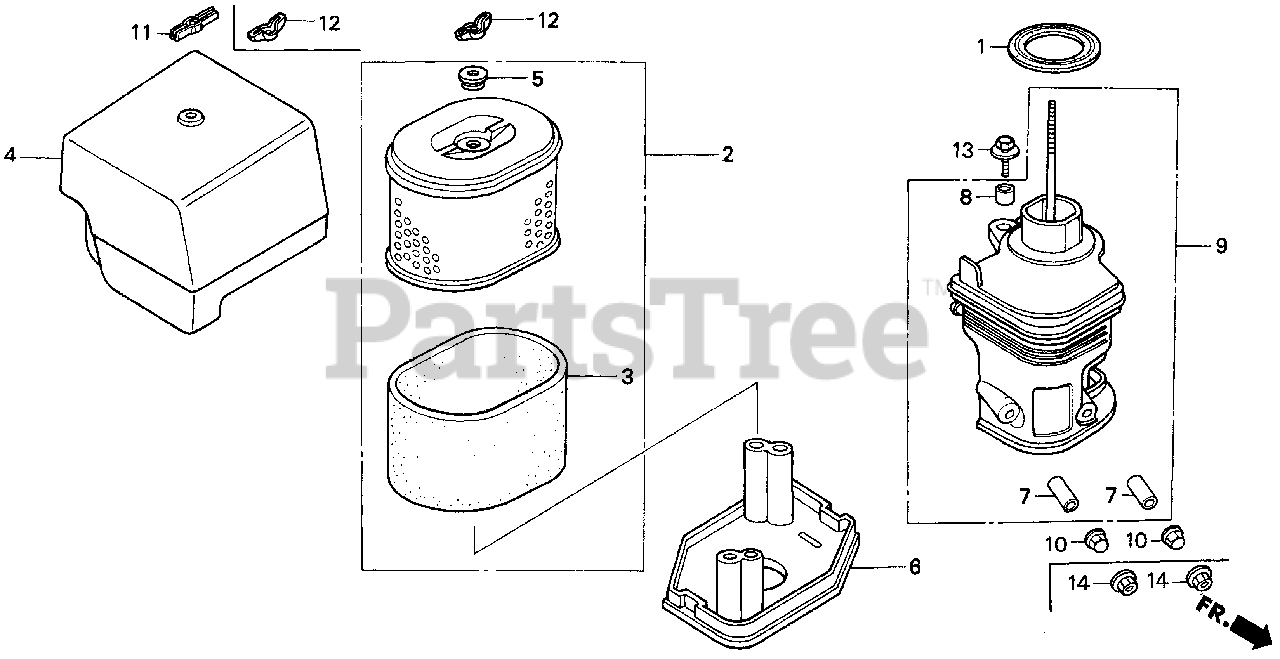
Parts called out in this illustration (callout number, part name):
1	GASKET, ELBOW
2	ELEMENT, AIR CLEANER (DUAL)
3	FILTER (OUTER)
4	COVER, AIR CLEANER
5	GROMMET, AIR CLEANER
7	COLLAR, AIR CLEANER
8	COLLAR B, AIR CLEANER
9	ELBOW, AIR CLEANER
11	WINGNUT (6MM)
12	WINGNUT, TOOL BOX SETTING
13	BOLT-WASHER (6X22)
13	BOLT-WASHER (6X20)
14	NUT, FLANGE (6MM)
